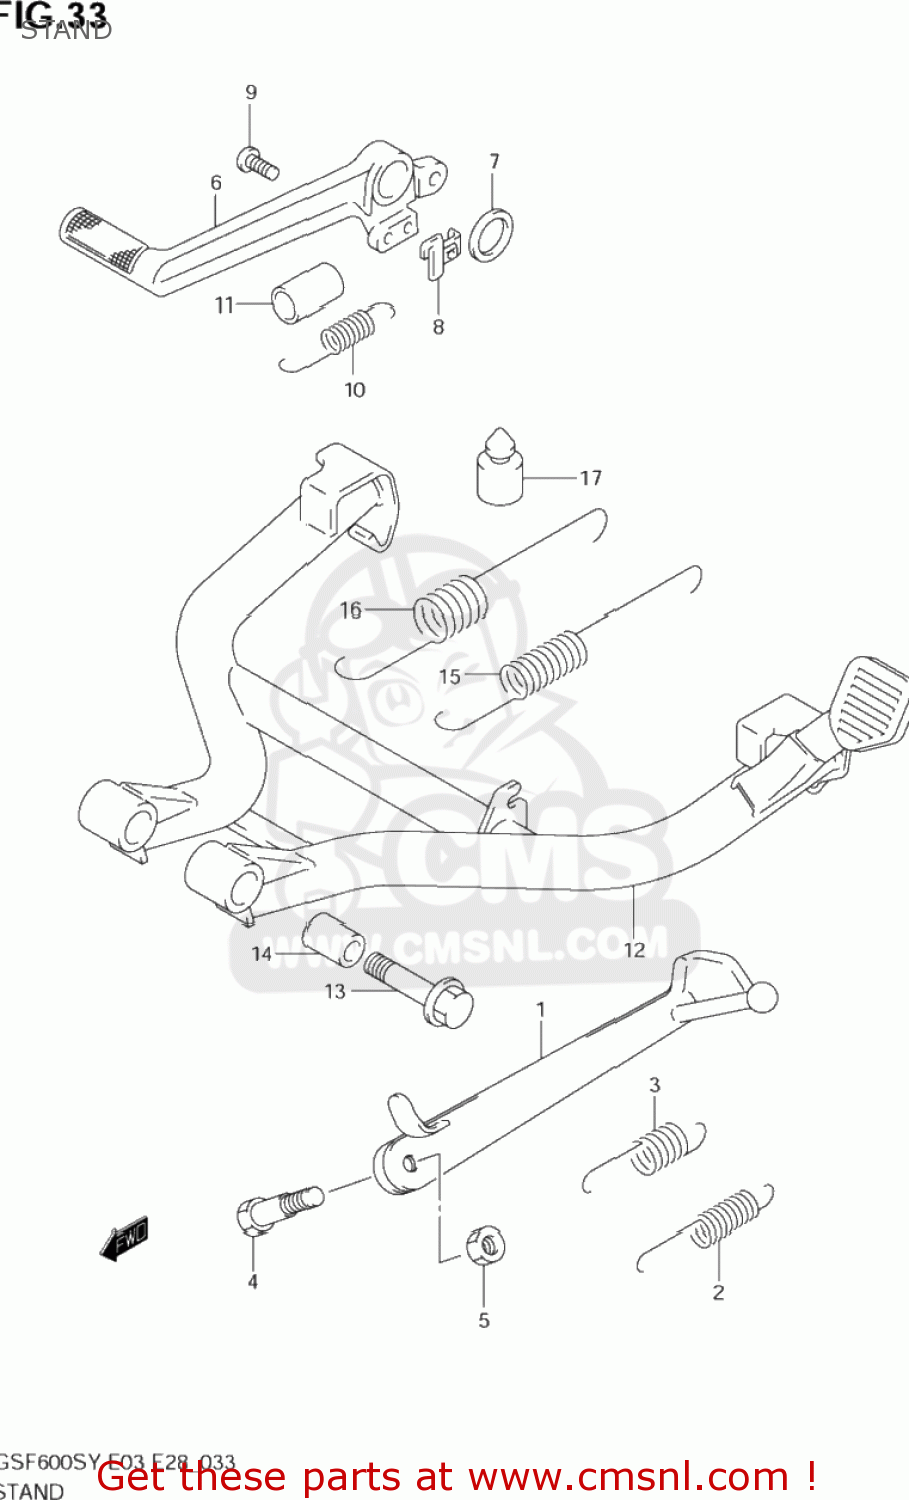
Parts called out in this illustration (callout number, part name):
1	STAND,PROP
2	SPRING
3	SPRING
4	BOLT(10X37.5)
5	NUT
6	PEDAL,BRAKE
7	WASHER(18X24X1)
8	BRACKET,STOP LAMP SWITCH SPR
9	SCREW
10	SPRING
11	TUBE,BRAKE SPRING GUIDE
12	STAND,CTR
13	BOLT(10X48)
14	SPACER(10X16X25.5)
15	SPRING
16	SPRING OUTER
17	CUSHION
